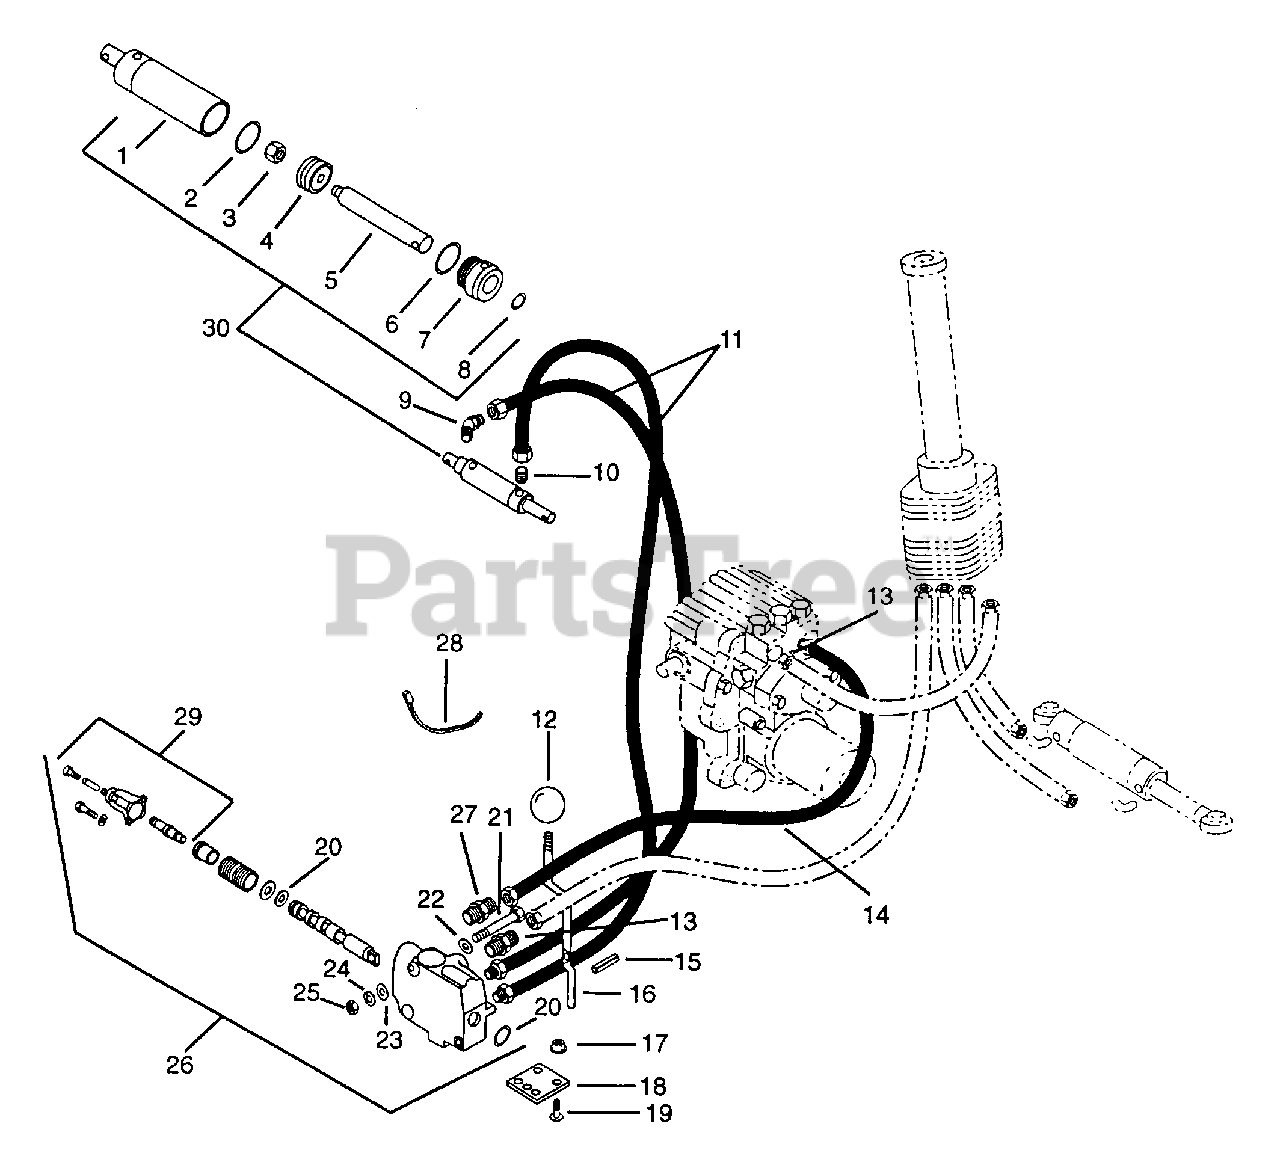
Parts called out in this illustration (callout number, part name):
1	CYLINDER
2	O-RING 1.625X2.000
3	NUT-LK .375-24 PL
6	O-RING 1.937X2.125
7	ROD CAP
8	O-RING 1.000X1.250X
9	ADAPTER 45 9/16 TO 1/4
10	ADAPTER
11	HYDRAULIC HOSE
12	KNOB-STEERING LOCK
13	CONNECTOR
14	HYDRAULIC HOSE
15	PIN-GRV .250X.75 TP B PL
16	CONTROL ROD
17	NUT-FLG. .312-18 PL
18	PIVOT BRACKET
19	BLT-RDHDSQSHNK .31-18X.50 YZ
20	SEAL KIT
21	BLT-HEX .25-20X2.25 GR2
22	WSHR-FL-STL .250X.562X.125 PL
23	WSHR-FL-STL.281X.62X.065 PL
24	WSHR-LK .250X.077 HVY PL
25	NUT-HEX .250-20 PL
26	HYDRAULIC CONTROL VALVE
27	CONNECTOR - EXTENDED
28	CABLE TIE LG 7-3/4
29	DETENT CAP REPAIR KIT
30	CYLINDER ASSEMBLY (LIFT)
